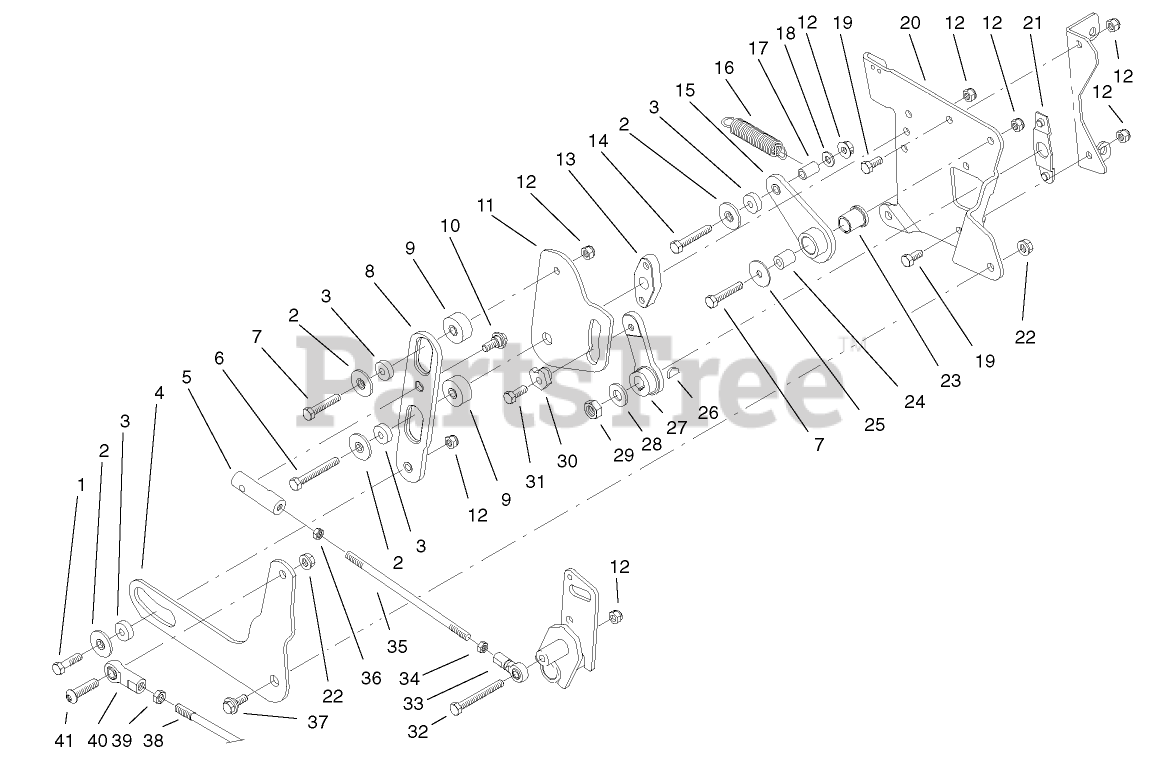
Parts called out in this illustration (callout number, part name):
1	SCREW-HH
2	RETAINER-BEARING
3	BEARING-BALL
4	SLIDER-LIFT
5	END-ROD, RH
6	SCREW-HH
7	SCREW-HH
8	SLIDER-CONTROL, SPEED
9	STANDOFF-CAM PLATE
10	BOLT-SHOULDER
11	PLATE-CAM
12	NUT-LOCK, NI
13	STANDOFF-SLIDER
14	SCREW-HH
15	ARM-RETURN TO NEUTRAL
16	SPRING-IDLER
17	STANDOFF-SPRING
18	WASHER-PLAIN
19	SCREW-HH
20	PLATE-CONTROL
21	LOCATOR-CONTROL PLATE
22	NUT-HEX
23	BUSHING-FLANGED
24	SPACER
25	WASHER-FLAT
26	KEY-WOODRUFF
27	ARM-CONTROL, SPEED
28	WASHER-FLAT
29	NUT-HEX
31	SCREW-THREAD LOCKING
32	SCREW-HH
33	END-ROD, RH
34	NUT-JAM
35	ROD-SLIDER TO PIVOT
36	NUT-JAM
37	BOLT-SHOULDER
38	ROD-LIFT
39	NUT-HJ
40	END-ROD, FEMALE
41	SCREW-HSBH
